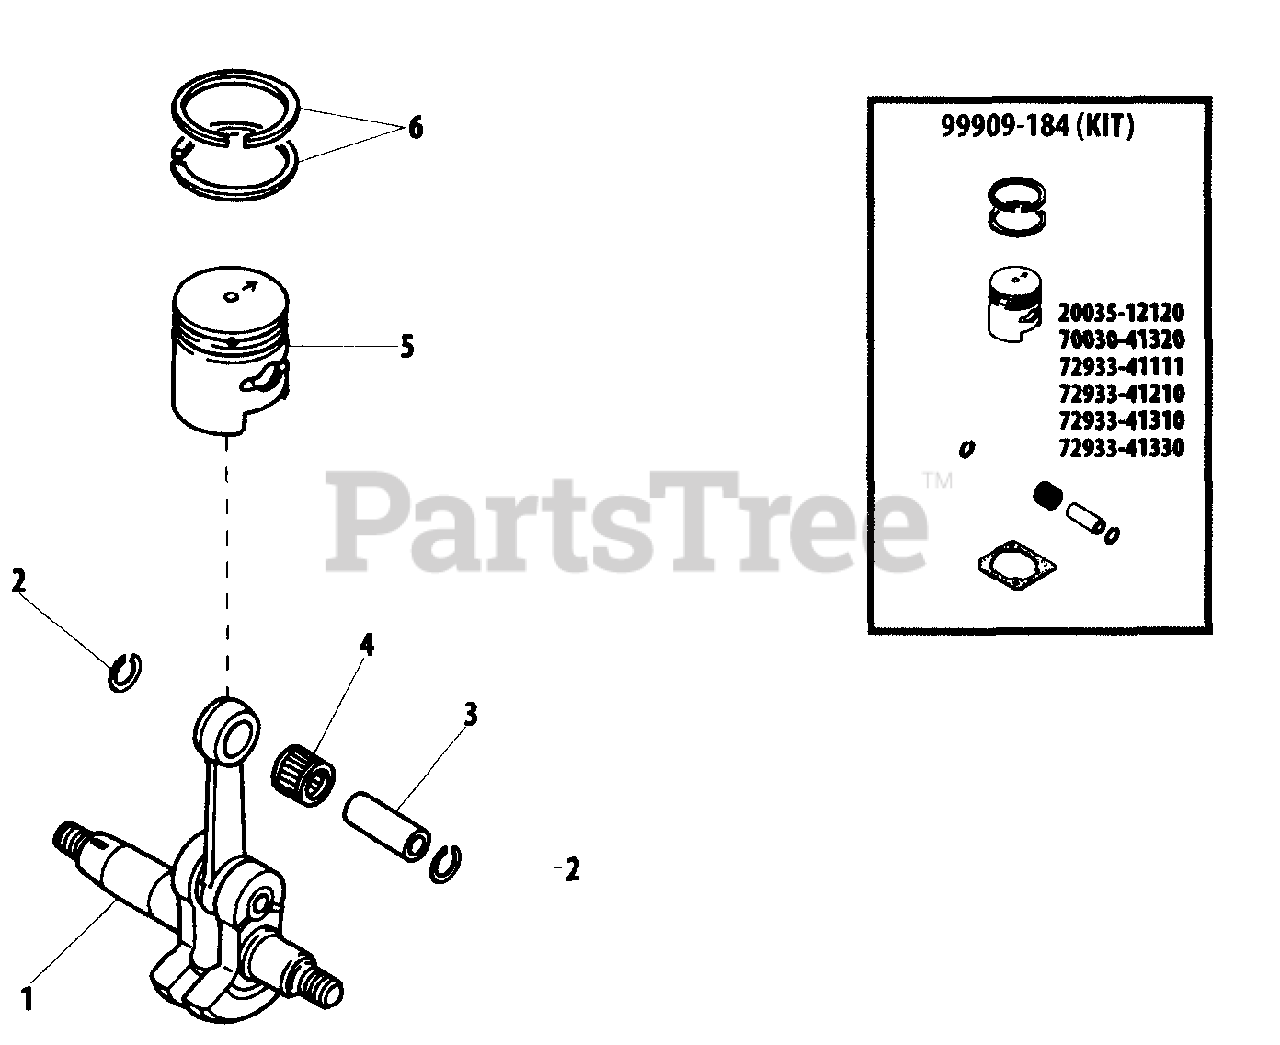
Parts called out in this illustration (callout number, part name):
1	CRANKSHAFT ASSY
2	RING, RETAINING
3	PIN, PISTON
4	BEARING, NEEDLE
5	PISTON
6	RING, PISTON
7	GASKET, CYLINDER
